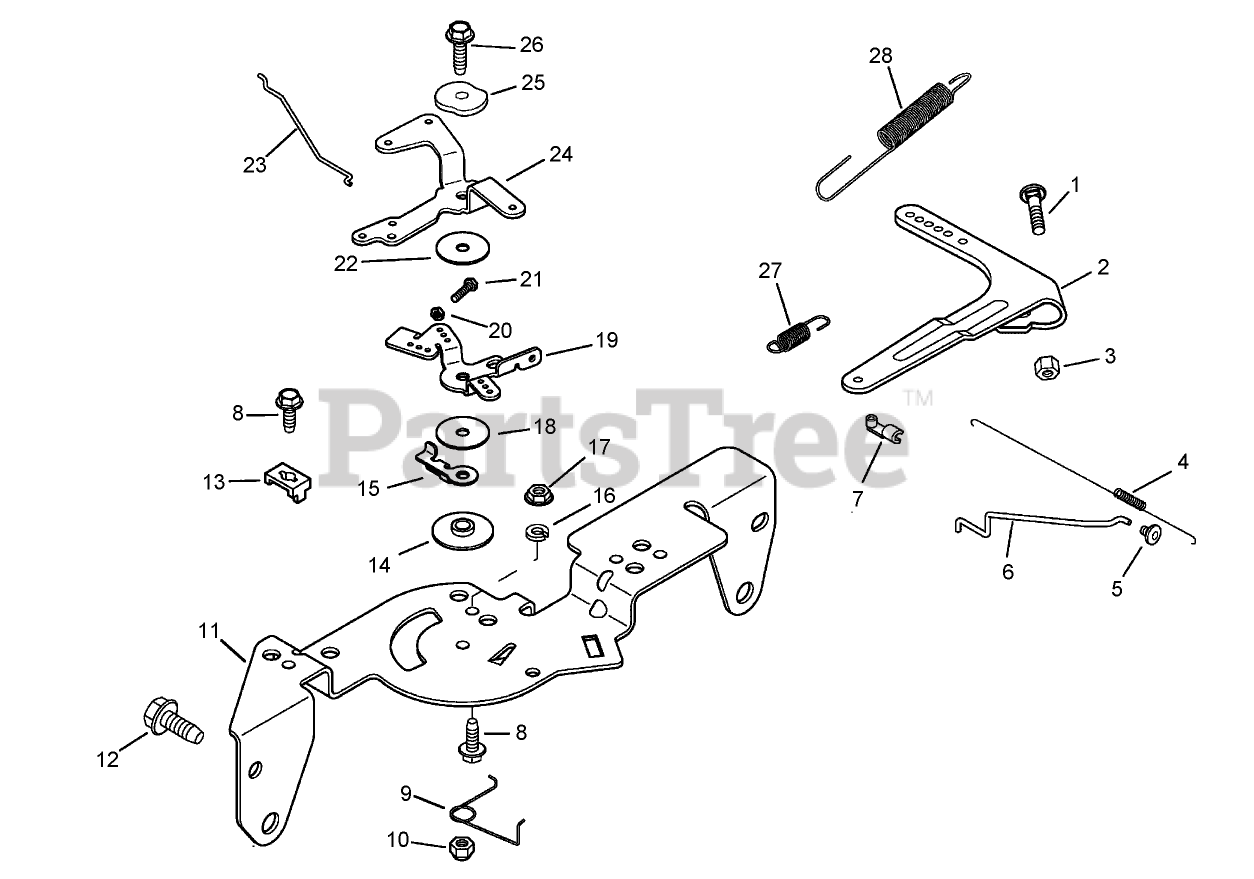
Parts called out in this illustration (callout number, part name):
1	BOLT-SQ NECK, RD HD (M6X1.0X25)
2	Lever-Governor
3	NUT-FLANGE (M6X1.0)
4	SPRING-LINKAGE
5	BUSHING-LINKAGE, THROTTLE
6	Linkage-Throttle
7	BUSHING-RETAINING, LINKAGE
8	SCREW-FLANGE, THREAD FORMING (M5X0.8X16)
9	SPRING-RETURN, CHOKE
10	NUT-LOCK (M5X.8)
11	Bracket-Control
12	SCREW-FLANGE, THREAD FORMING (M6X1.0X16)
13	CLAMP-CABLE
14	CONTROL SPACER ASM
15	LEVER-ACTUATOR, THROTTLE
16	Washer-Lock (.25)
17	Nut-HF (M5x0.8)
18	WASHER-FLAT (5MM)
19	Lever-Control, Throttle
20	NUT (M4X0.7)
21	Screw (M4x0.7x30)
22	WASHER-FLAT (5.5MM)
23	Linkage-Choke
24	LEVER-CHOKE
25	WASHER-SPRING (1/4)
26	SCREW-FLANGE, THREAD FORMING (M5X.8X20)
27	SPRING-GOVERNOR
28	Spring-Governor (ORANGE)
